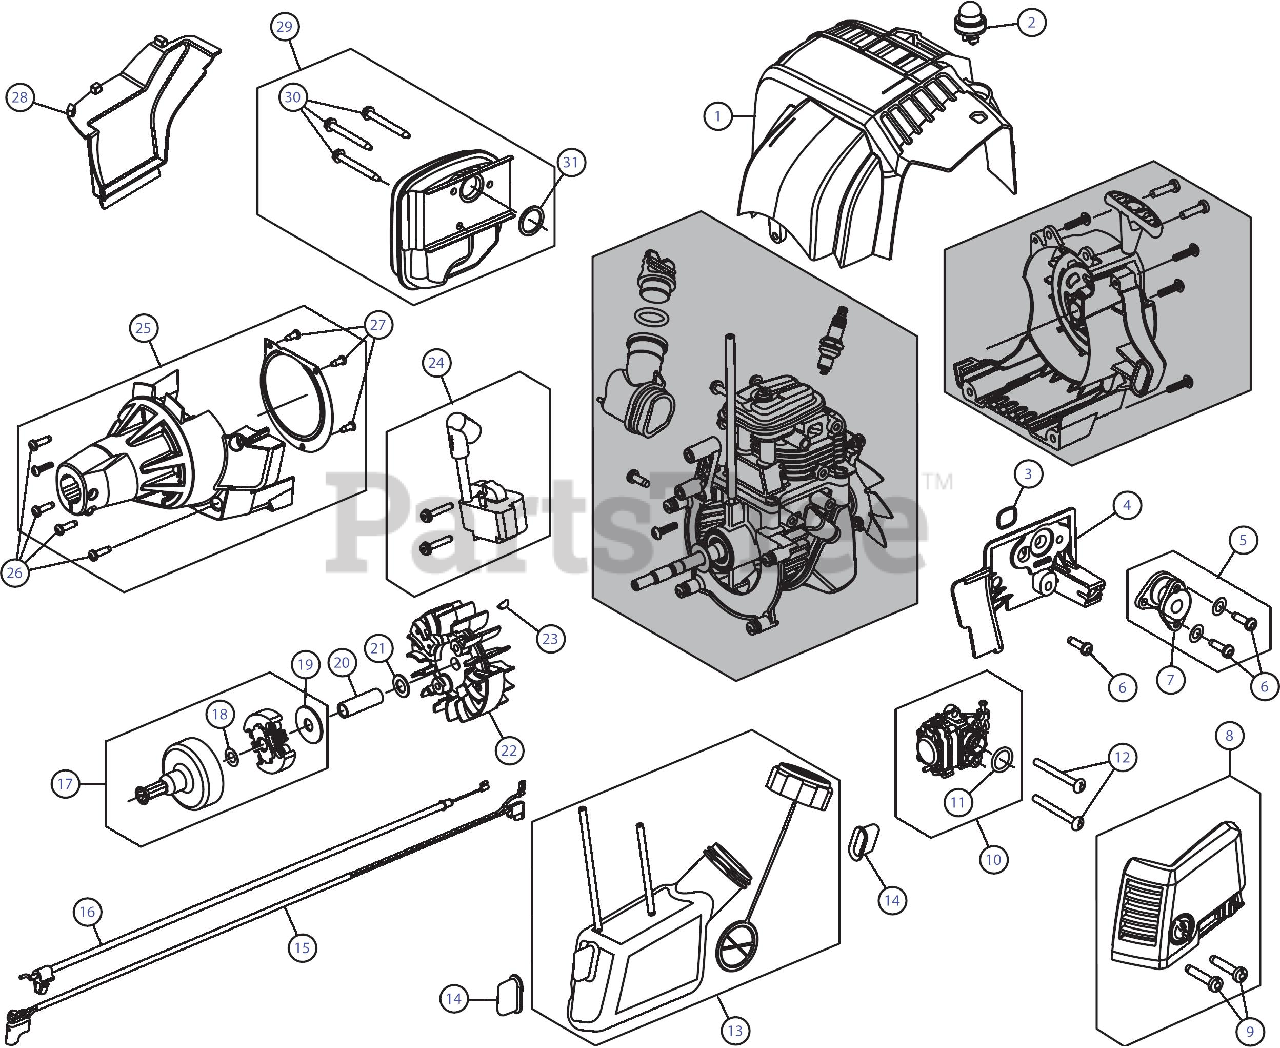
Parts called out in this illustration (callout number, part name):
1	Top Housing
2	Air Purge Primer
3	O-Ring
4	Intake Port
5	Boot Assembly (Incl. 6 & 7)
6	Screw
8	Air Cleaner Assembly
10	Carburetor Assembly (Incl. 11)
13	Fuel Tank Assembly
14	Fuel Tank Pad
15	Lead Wire
16	Throttle Cable
17	Clutch Assembly (Incl. 18 & 19)
18	Thrust Washer
19	Clutch Washer
20	Spacer
21	Washer
22	Flywheel
24	Module Assembly
25	Clutch Cover Assembly (Incl. 26 & 27)
27	Screw
28	Rear Engine Cover
29	Muffler Assembly (Incl. 30 & 31)
31	Muffler Gasket
